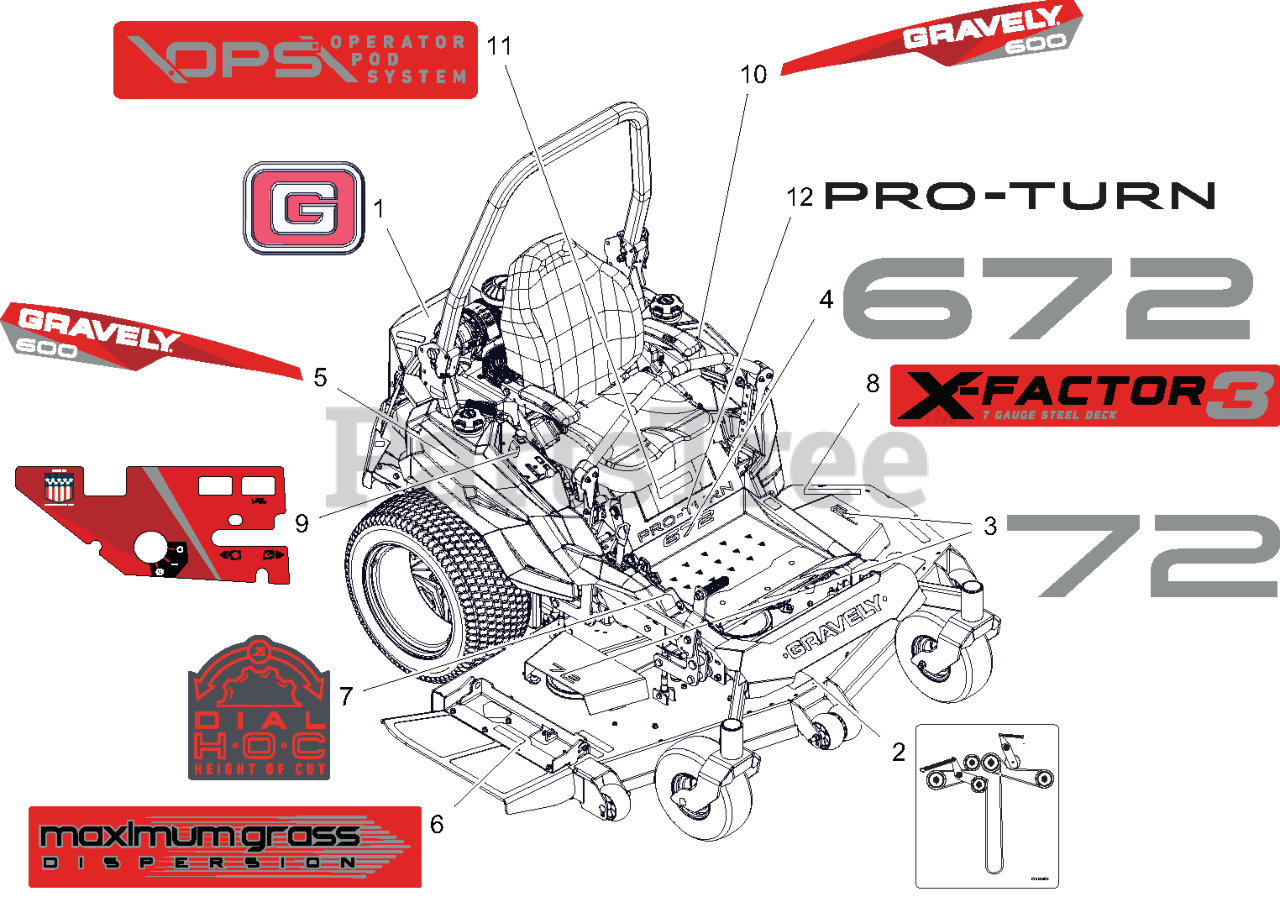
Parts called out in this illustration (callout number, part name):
1	DECAL, GRAVELY BRAND
2	DCL,BELT ROUTE-RH BK-SIDE IDLR
3	DECAL, DECK - 72
4	DECAL, PT672
5	DECAL, GRAVELY TANK - RH
6	DECAL, DECK - MAX GRASS
7	DECAL, COVER - HOC
8	DECAL, DECK - X-FACTOR 3
9	DECAL, CONTROL PANEL
10	DECAL, GRAVELY TANK - LH
11	DECAL, OPS
12	DECAL, PRO TURN
